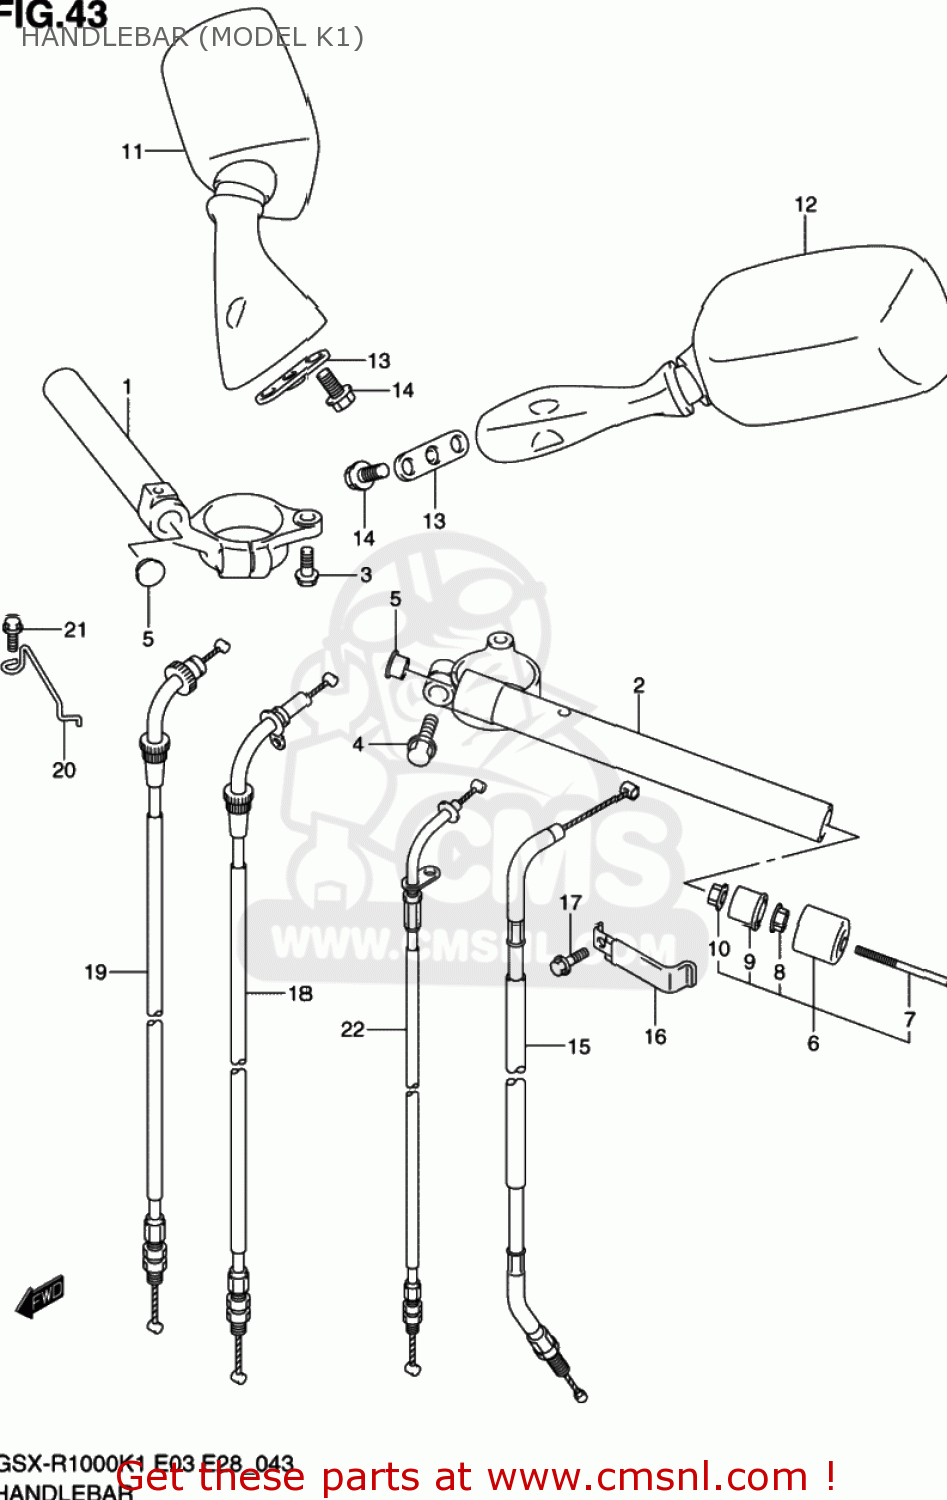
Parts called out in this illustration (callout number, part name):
1	HANDLEBAR,R
2	HANDLEBAR,L
3	BOLT
4	BOLT,HANDLEBAR
5	PLUG(OD:17)
6	BALANCER,HANDLEBAR
7	SCREW
8	NUT
9	EXPANDER,HANDLE BALANCER
10	NUT
11	MIRROR ASSY,RR VIEW,R
12	MIRROR ASSEMBLY,REAR VIEW
13	CUSHION,RR VIEW MIRRORR
14	BOLT,G/S SWITC
15	CABLE ASSY,CLUTCH
16	CLAMP,WIRING HARNESS
17	BOLT
18	CABLE ASSY,THROTTLE NO.1
19	CABLE ASSY,THROTTLE NO.2
20	GUIDE, CABLE
21	BOLT
22	CABLE,STARTER
